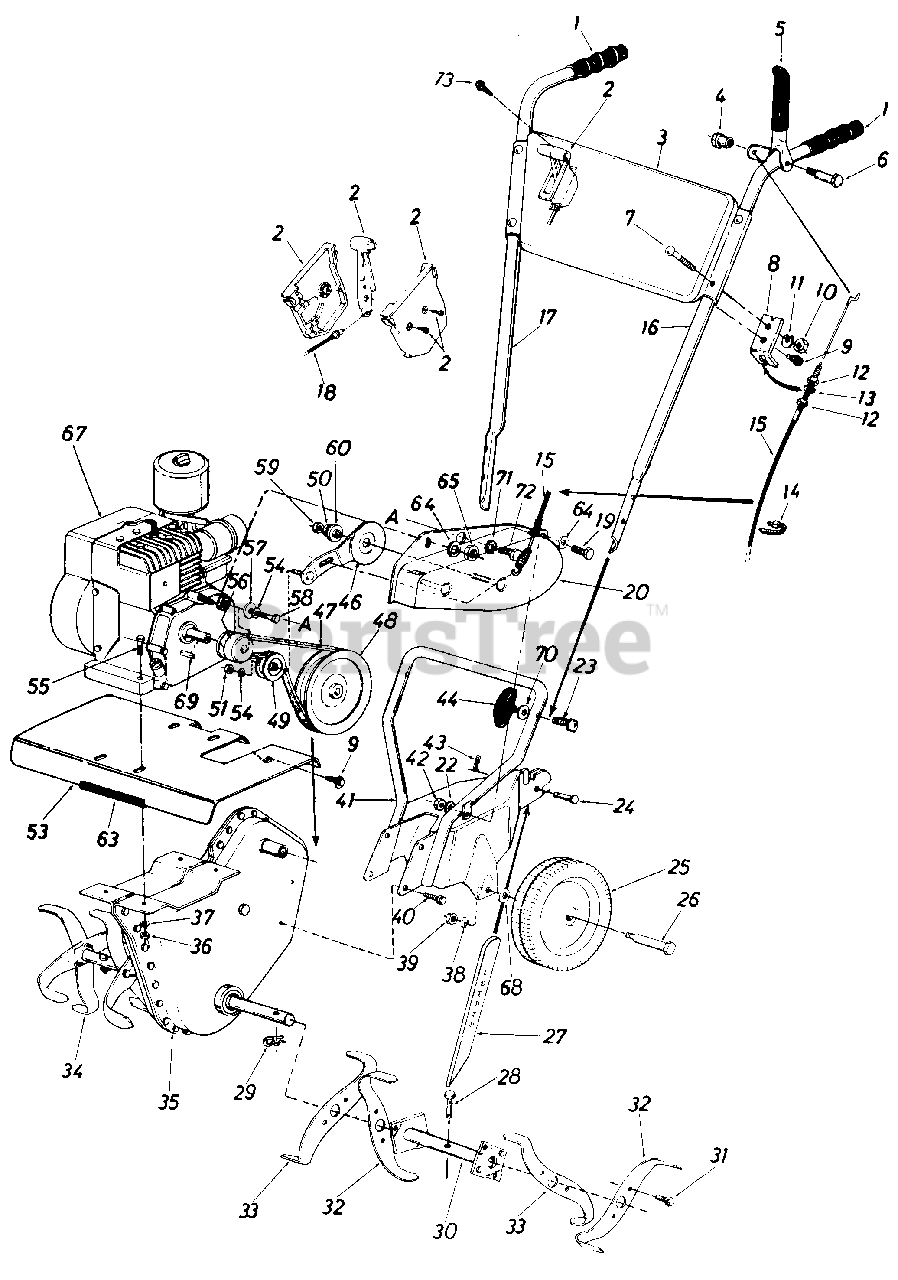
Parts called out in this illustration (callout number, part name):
2	Throttle Control Box Ass'y.
3	Handle Panel
4	Shoulder Nut
5	Clutch Grip Ass'y.
6	Shoulder Bolt 3/8 x 1.160" Lg.
7	Carriage Bolt 5/16-18 x 1.5" Lg.*
8	Cable Support Bracket
9	Hex Wash. Hd. Self-Tap Scr. 1/4-20 x .50" Lg.
10	Hex Nut 5/16-18 Thd.*
11	L-Wash 5/16" I.D.*
12	Hex Jam Nut 5/16-24 Thd.
13	L-Wash. 5/16" I.D.*
15	Clutch Control Cable
19	Hex Bolt 1/4-20 x .75" Lg.*
20	447 Belt Cover Ass'y.
22	L-Wash. 1/4" I.D.*
23	Curved Hd. Bolt 5/16-18 x 1.75" Lg.
25	Wheel Ass'y. Comp. 7.0" x- 1.5
26	Shoulder Bolt
29	Hairpin Cotter
36	Hex Nut 5/16-18 Thd.*
37	L-Wash. 5/16" I.D.*
38	L-Wash. 3/8" I.D. (Heavy Duty)
39	Hex Cent. L-Nut 3/8-16 Thd.
40	Hex Wash. Hd. Self-Tap Scr. 5/16-18 x .50" Lg.
43	Internal Cotter Pin
44	Hand Knob
46	Idler Arm Ass'y.
47	Belt 3/8" x 29" Lg.
48	Chain Case Pulley 5-1/2 x 1/2"
50	L-Wash. 5/16" I.D.*
51	Hex Nut 3/8-24 Thd.*
53	Tine Shield
54	L-Wash. 3/8" I.D.*
55	Hex Bolt 5/16-18 x 1.50" Lg.
56	Engine Pulley 3/8 V x .75 I.D. x 2" O.D.
57	Fl-Wash. .385" I.D. x 1.00" O.D.
58	Hex Bolt 3/8-24 x 1.00" Lg.*
59	Hex Nut 5/16-18 Thd.*
60	Shld. Spacer .50" Dia. x .133
63	Trim Strip-4"
64	Fl-Wash. .281" I.D. x .500" O.D.
65	Hex Cent. L-Nut 1/4-20 Thd.
67	Engine
68	Bell-Wash.
69	Square Key 3/16 x 3/4" Lg.
71	Ext. L-Wash. 1/2" I.D.
72	Hex Bolt 1/2-20 x .75" Lg.
73	Self-Tap Screw #10 x .5" Lg.
